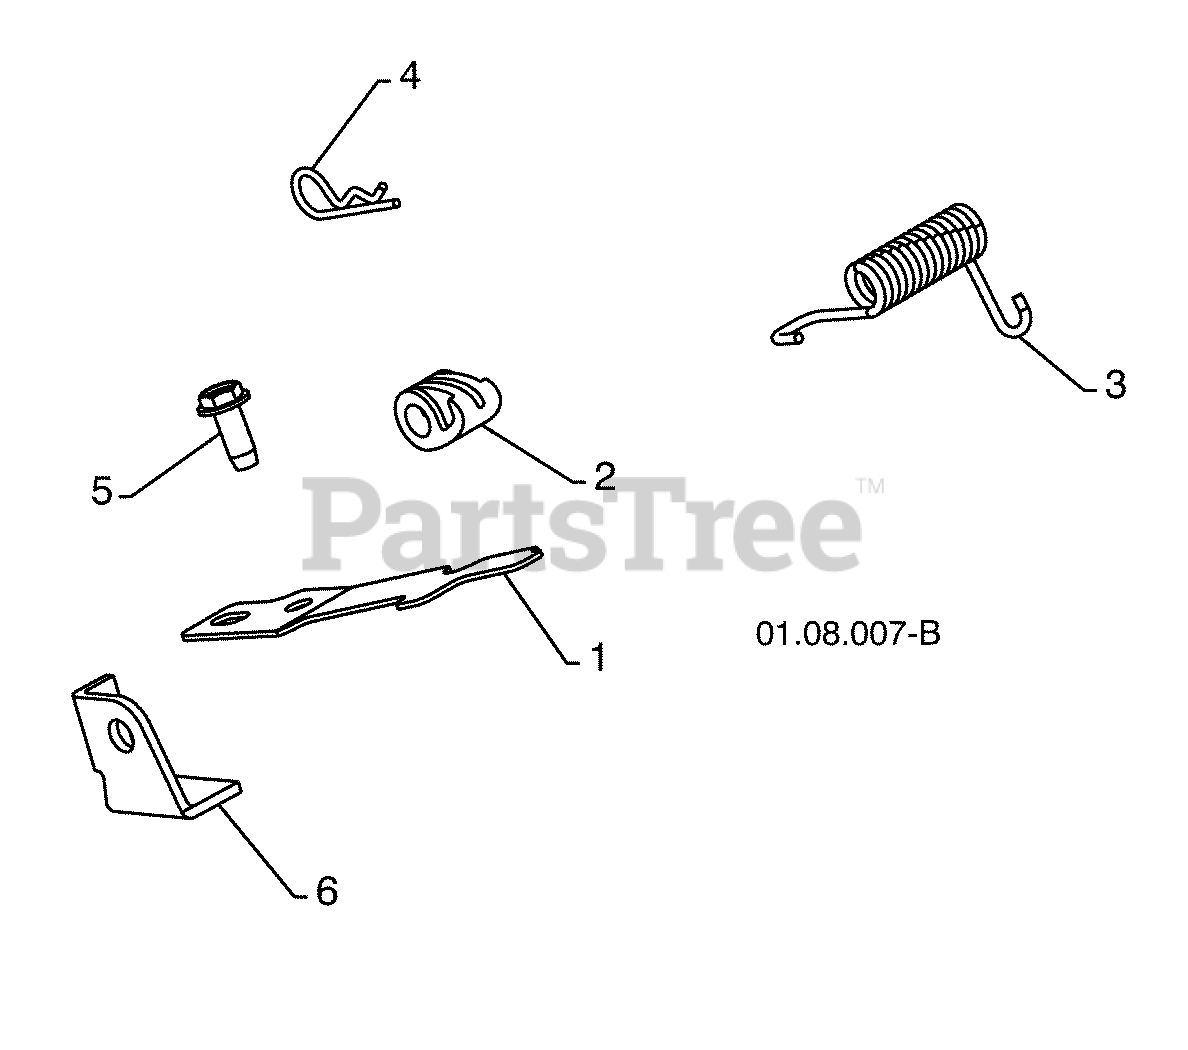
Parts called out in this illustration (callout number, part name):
1	INTERLOCK SPRING
2	INTERLOCK CAM
3	TORSION SPRING
5	SCREW 1/4-20 X .625
6	INTERLOCK STOP
